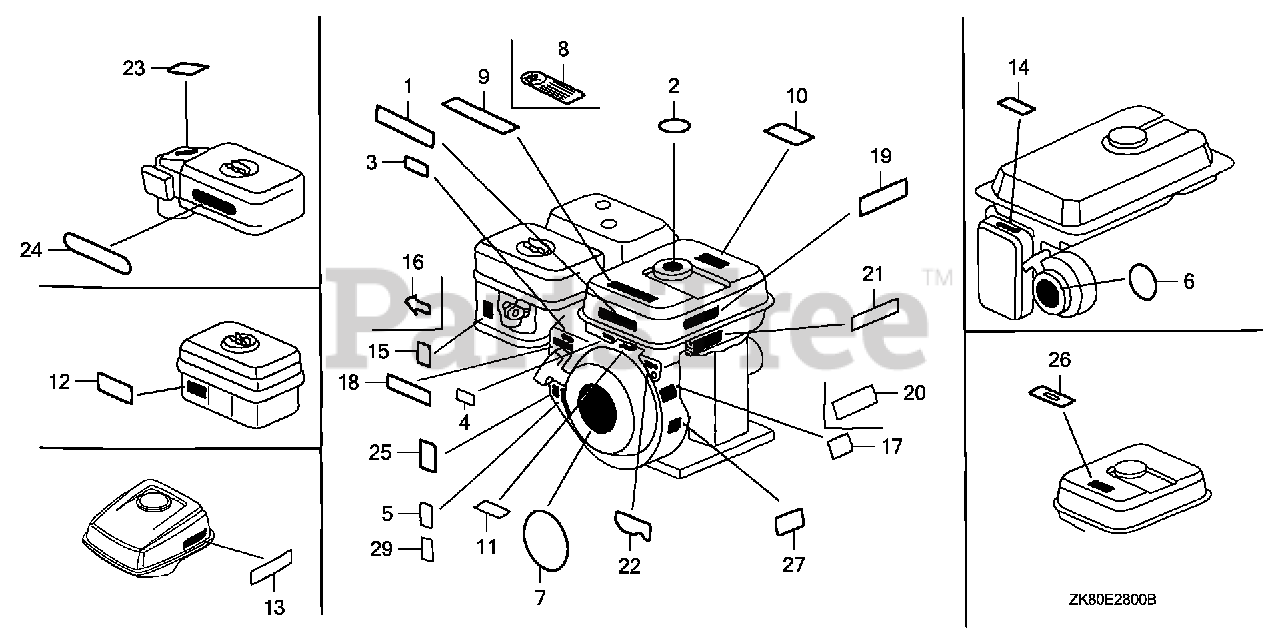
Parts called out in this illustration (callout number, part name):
1	LABEL, CAUTION (ENGLISH, ETC.)
7	EMBLEM (GX160)
15	MARK, CHOKE
19	MARK, OIL ALERT (ENGLISH)
